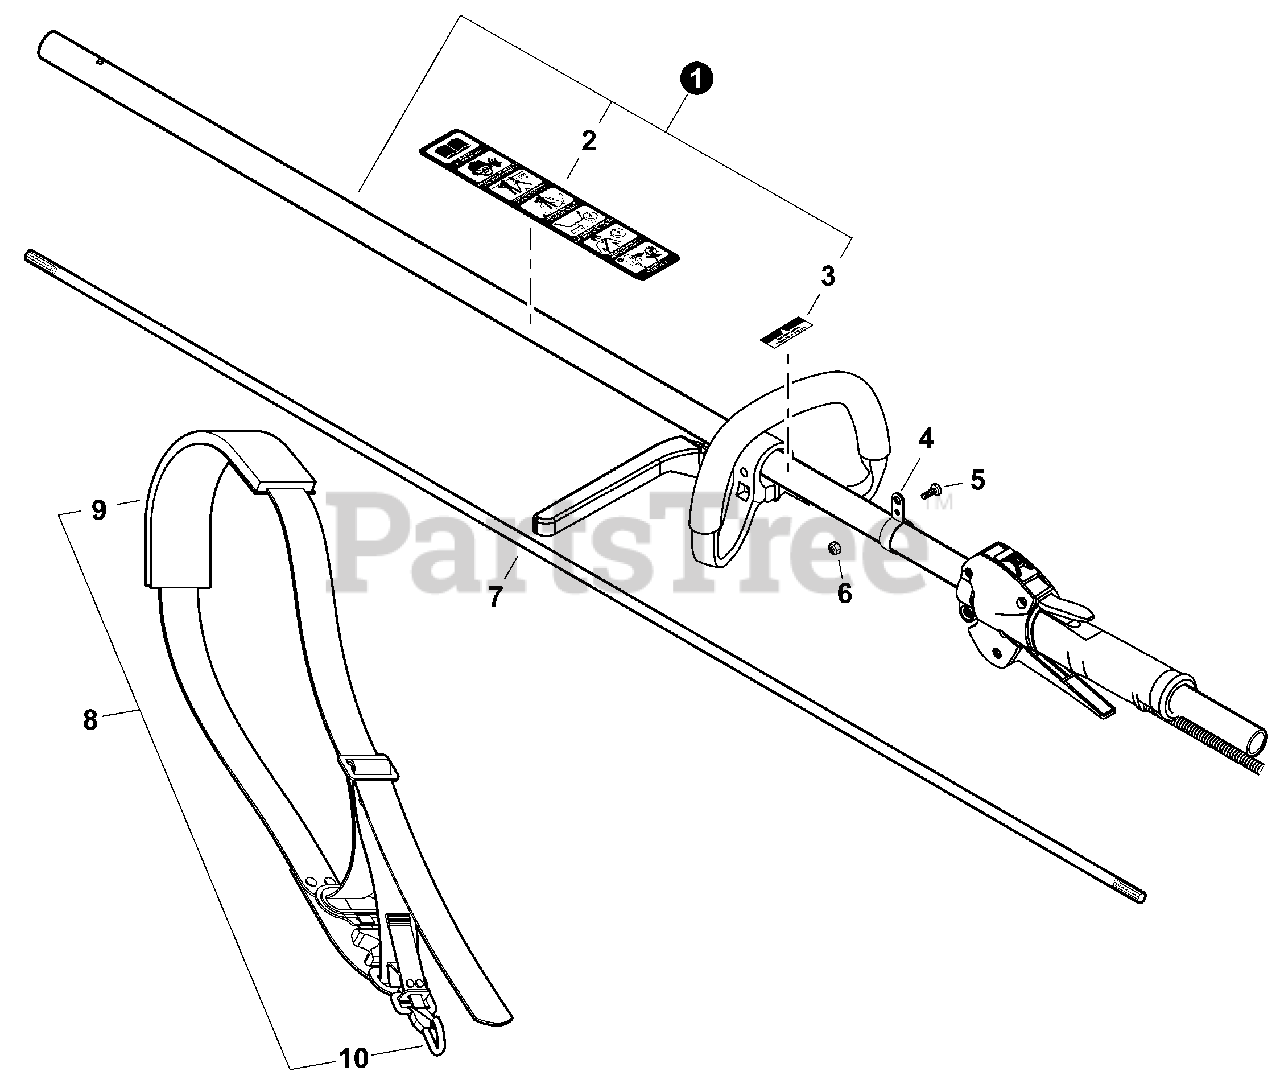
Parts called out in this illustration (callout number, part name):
1	MAIN PIPE ASSY
2	LABEL, CAUTION (BLADE CAPABLE)
3	LABEL, HANDLE
5	BOLT 5×12
7	MAINSHAFT
8	HARNESS ASSY, SHOULDER
9	PAD, SHOULDER
10	HOOK, SNAP
